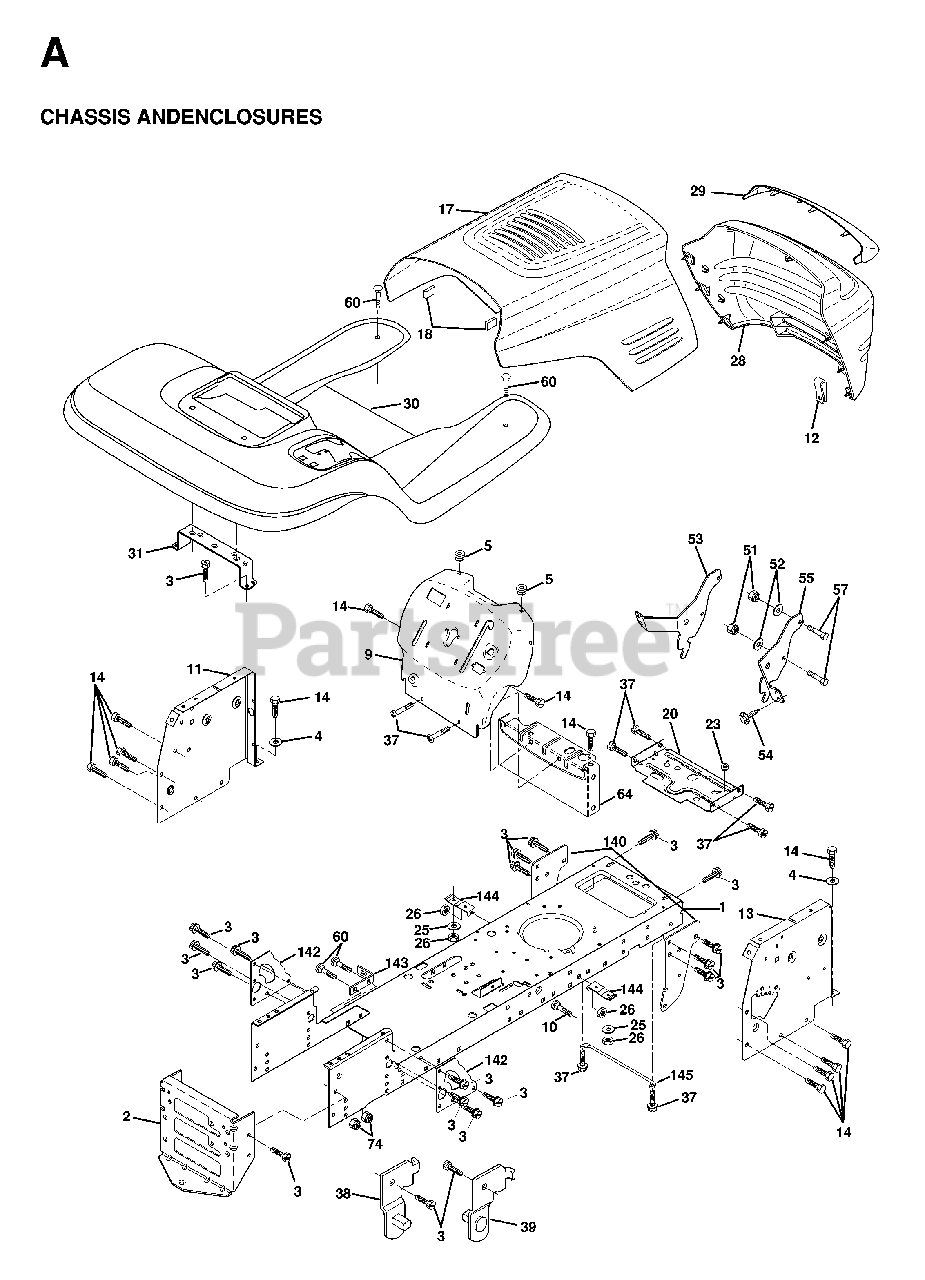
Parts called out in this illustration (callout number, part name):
2	STRETCH DRAWBAR
3	SCREW
5	BUMPER.RUBBER.HOOD
10	BOLT D
11	PANEL DASH LH
13	DASH PANEL
18	BUMPER HOOD T
20	PLATE MTG
23	GROMMET T
25	WASHER
26	NUT
38	BRACKET LH PIVOT
39	BRACKET RH PIVOT
51	LOCKNUT
57	BOLT
64	DASH LOWER
74	LOCKNUT
140	BRACKET SUSPENSION FRONT
142	PLATE REINFORCEMENT
143	BRACKET, SWAY BAR
144	BRACKET FOOTREST
145	ROD PIVOT CHASSIS/HOOD
